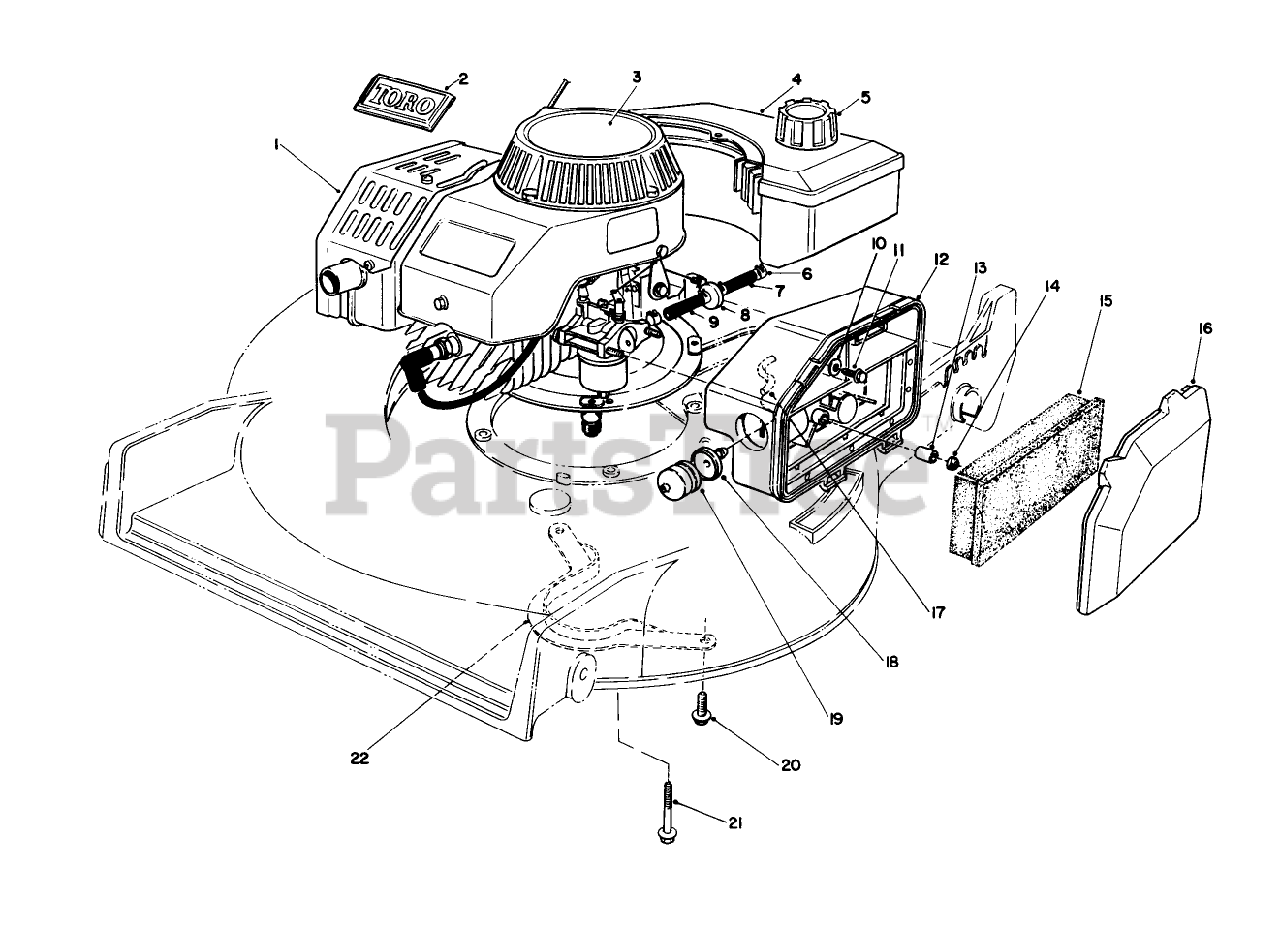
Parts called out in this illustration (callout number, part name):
5	GAS CAP ASM
6	CLAMP-FUEL LINE
7	HOSE-FUEL
8	FILTER-FUEL
9	HOSE-FUEL
10	WASHER-FLAT
11	SCREW-HH
13	SPACER
15	ELEMENT-AIR CLEANER
16	COVER-AIR CLEANER
17	HOSE-PRIMER F
18	BODY-PRIMER
20	SCREW-HHF
21	SCREW-HHF
